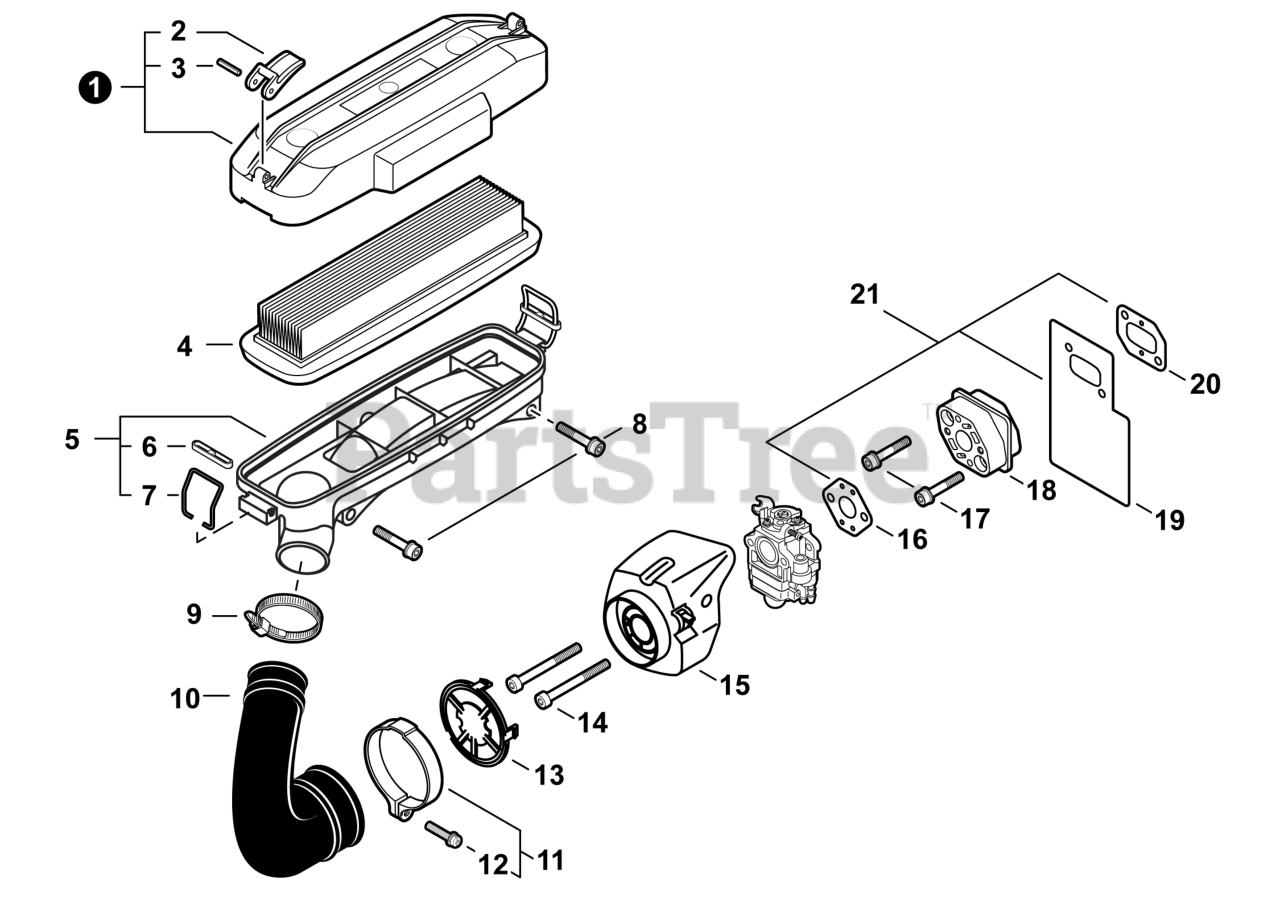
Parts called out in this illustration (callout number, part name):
1	COVER, AIR FILTER
2	LATCH, FILTER COVER
3	PIN, SPRING 3x25
4	FILTER, AIR
5	CASE ASSY, AIR FILTER
8	SCREW 5x35
9	CLAMP - BAND 33 MM /57 MM
10	PIPE, INTAKE
11	CLAMP KIT
12	SCREW 5x25
13	PLATE, PREVENT
14	BOLT 5x55
15	CASE ASSY, AIR FILTER
16	GASKET, INTAKE
17	BOLT 5x25
18	INSULATOR, INTAKE
19	HEAT SHIELD, INTAKE
20	GASKET, INTAKE
21	GASKET KIT
